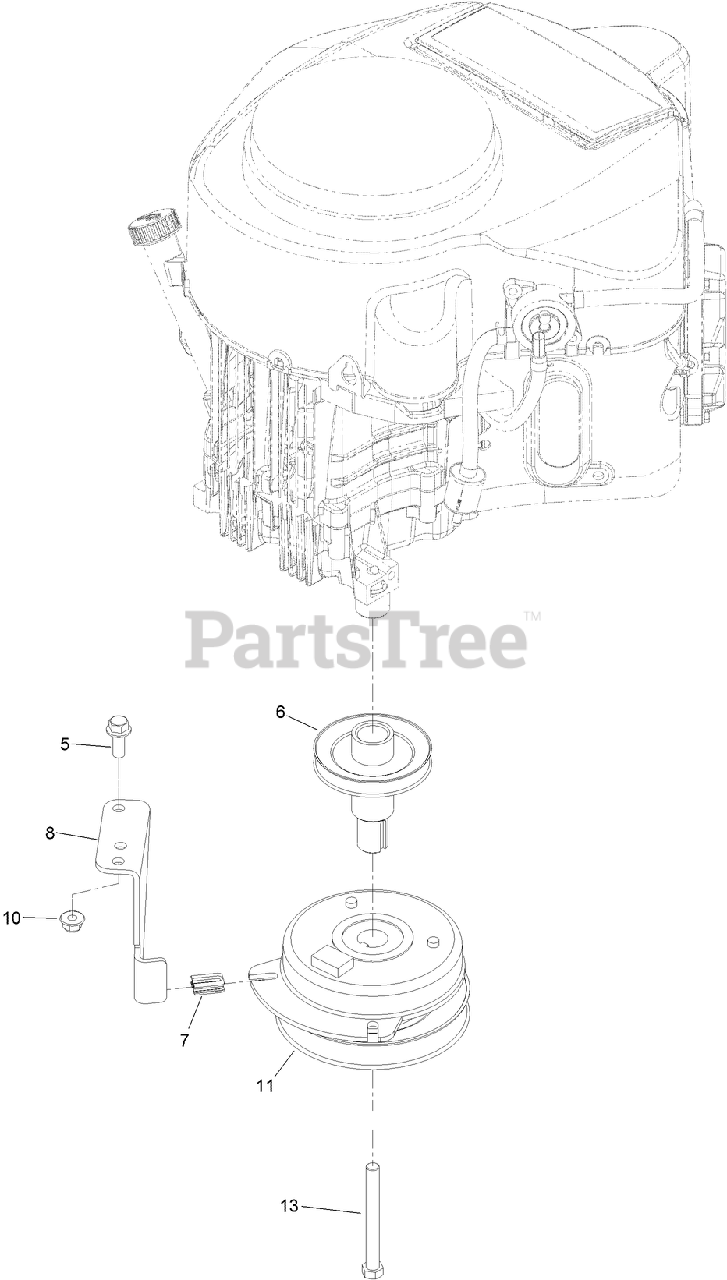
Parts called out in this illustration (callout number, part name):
5	SCREW-HHF
6	PULLEY-ENGINE
7	ISOLATOR-CLUTCH
8	STOP-CLUTCH
10	NUT-HF, NI
11	CLUTCH-PTO
13	SCREW-HH
